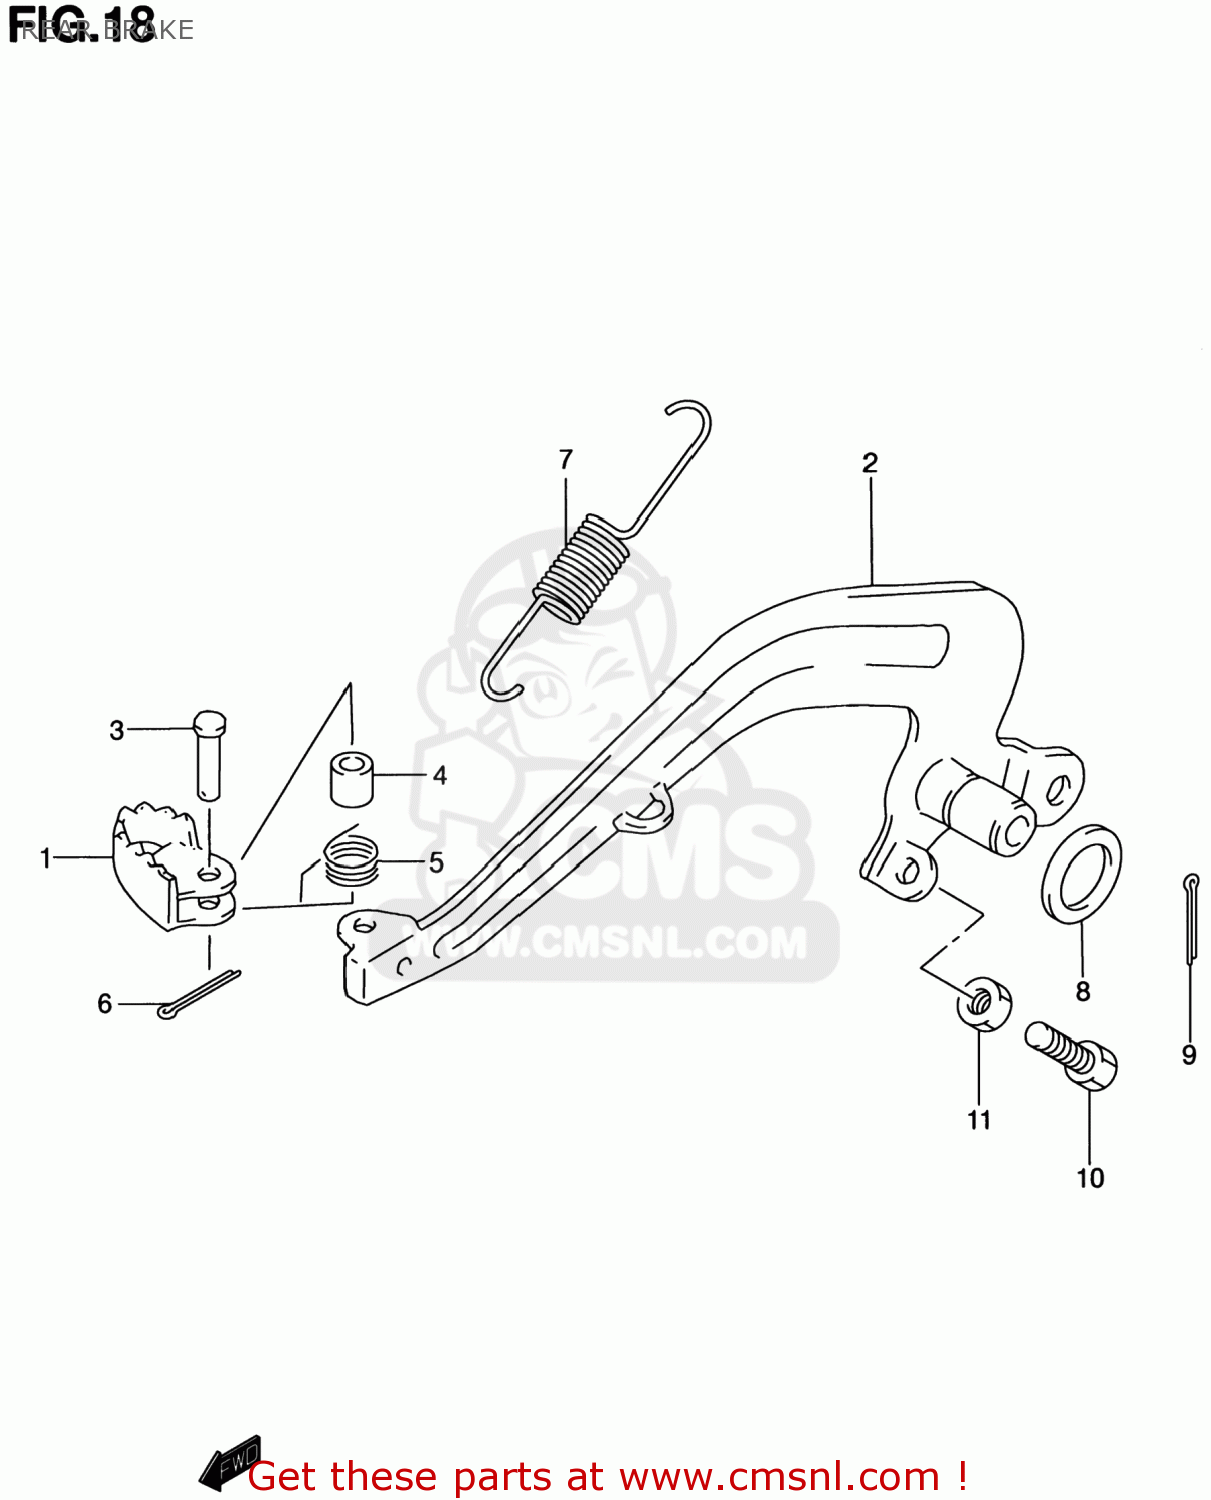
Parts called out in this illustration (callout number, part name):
1	PEDAL,BRAKE
2	ARM,BRAKE PEDAL
3	PIN
4	SPACER(6.5X9X6.5)
5	SPRING
6	PIN
7	SPRING
8	WASHER(15.5X24X2.3)
9	PIN, COTTER
10	SCREW(6X23)
11	NUT 6MM
